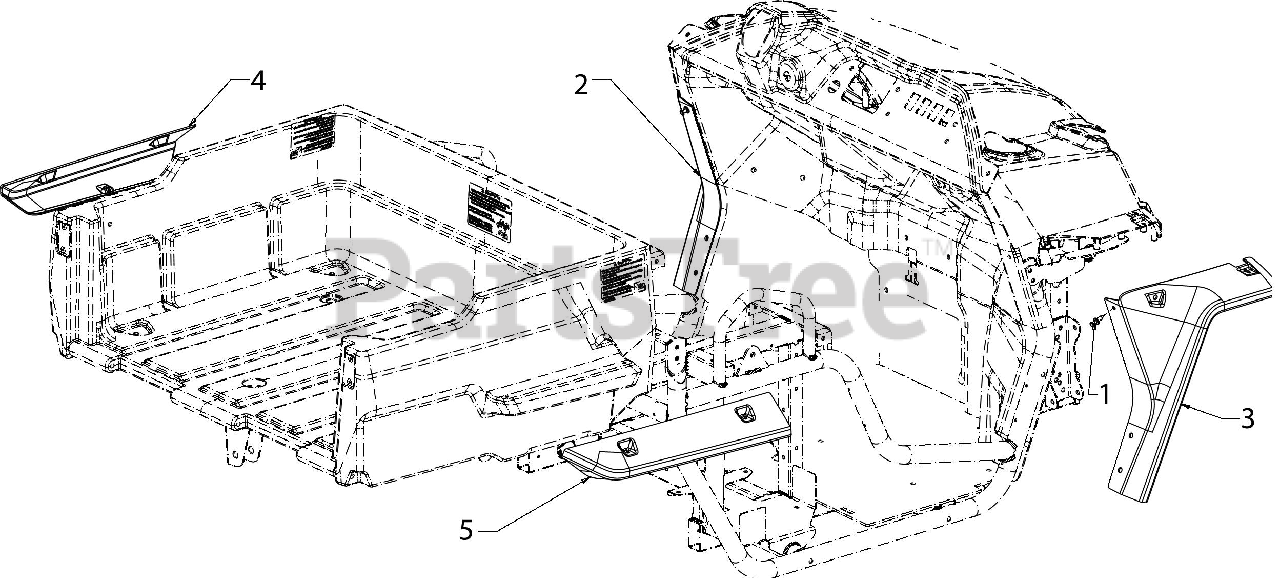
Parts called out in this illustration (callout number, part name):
1	PLASTIC RIVET
2	FRONT FENDER (LH) (RED)
3	FRONT FENDER (RH) (RED)
4	REAR FENDER (LH) (RED)
5	REAR FENDER (RH) (RED)
